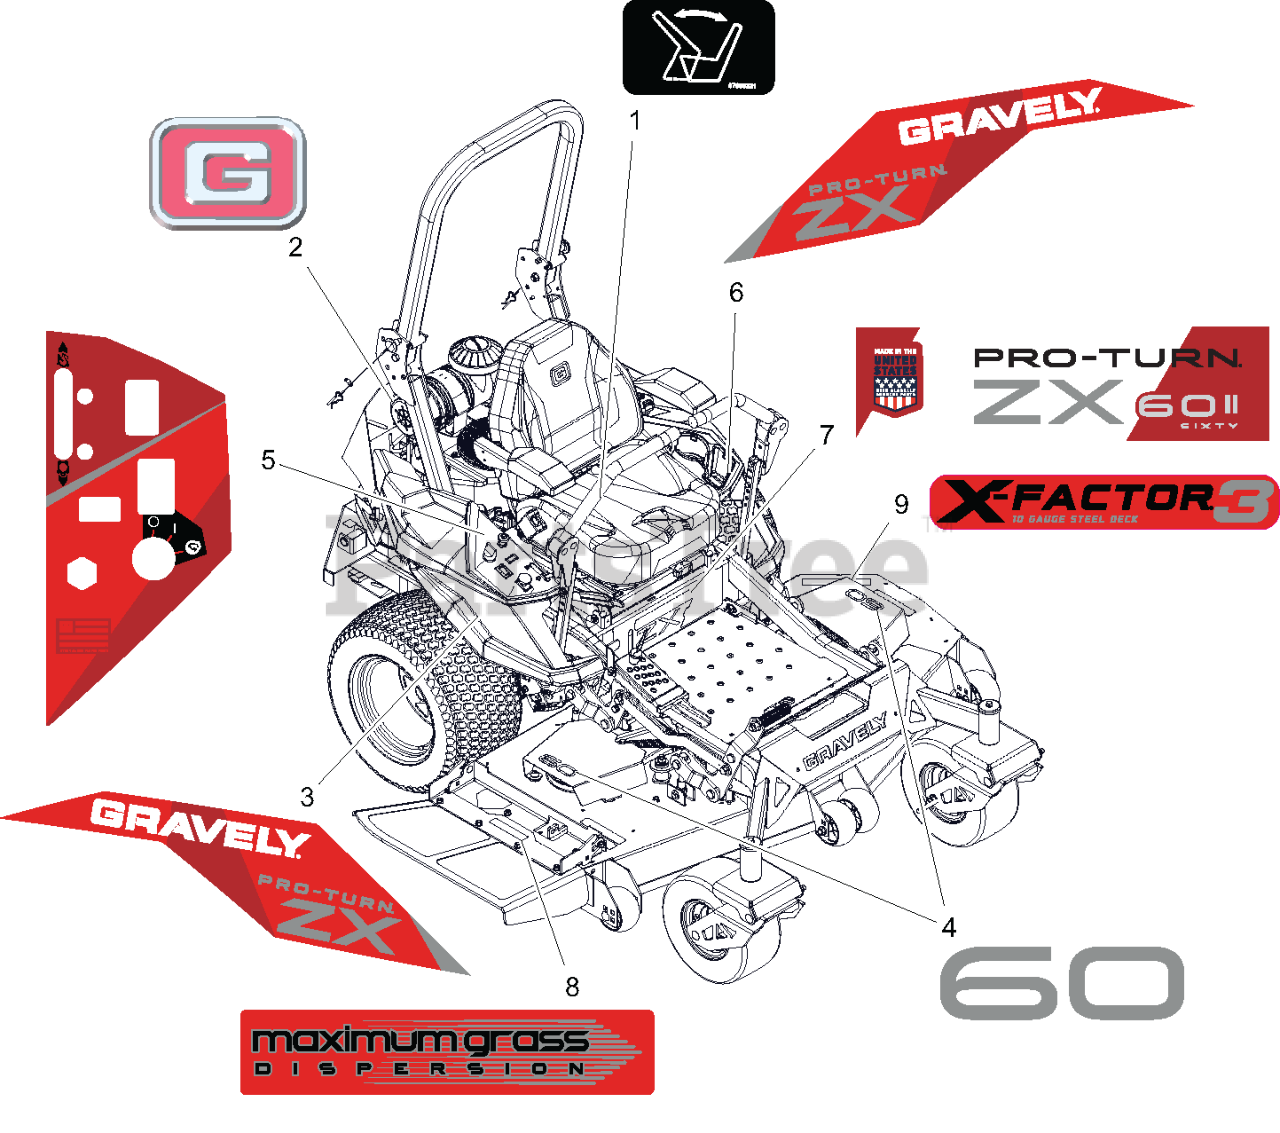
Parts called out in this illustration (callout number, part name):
1	DECAL - SEAT RELEASE
2	DECAL, GRAVELY BRAND
3	DECAL, FENDER RH - PTZX
4	DECAL, DECK - 60
5	DECAL, CONTROL PANEL
6	DECAL, FENDER LH - PTZX
7	DECAL, PTZX - 60
8	DECAL, DECK - MAX GRASS
9	DECAL, X-FACTOR 3
